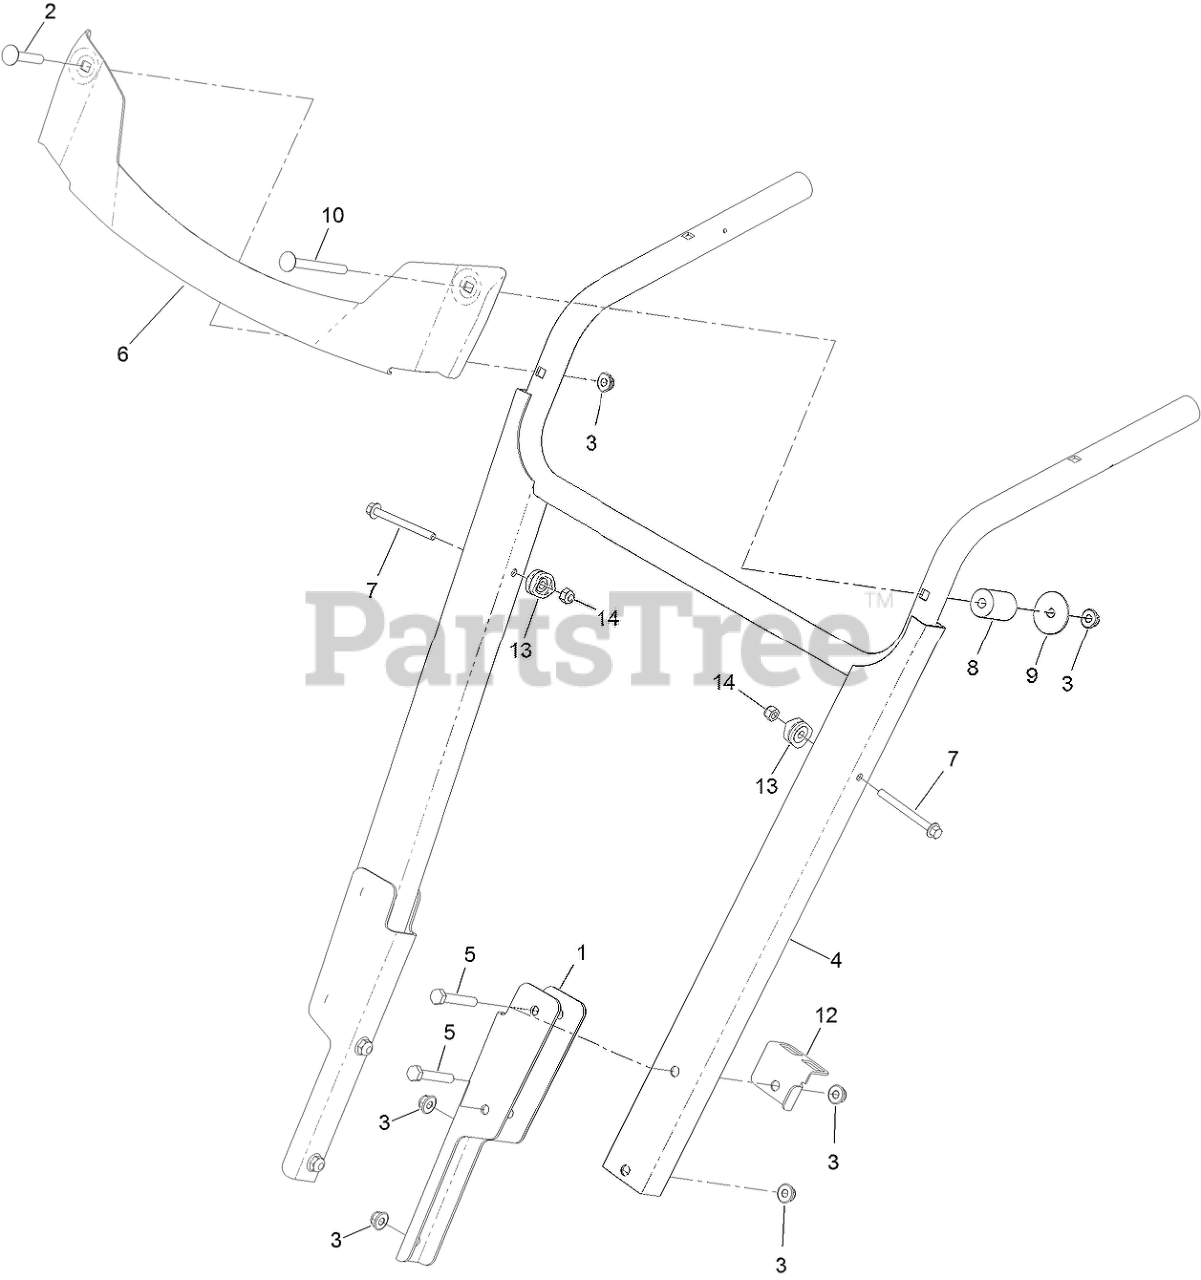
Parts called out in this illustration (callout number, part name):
1	BRACKET-HANDLE, LOWER
2	BOLT-CARR
3	NUT-HF
4	HD HANDLE ASM
5	SCREW-HH
6	TRIM-METAL, HD
7	SCREW-HHF
8	SPACER
9	WASHER-FLAT
10	SCREW-CARR
12	BRACKET-STICK, CLEANOUT
13	CLAMP-CABLE
14	NUT-HEX
